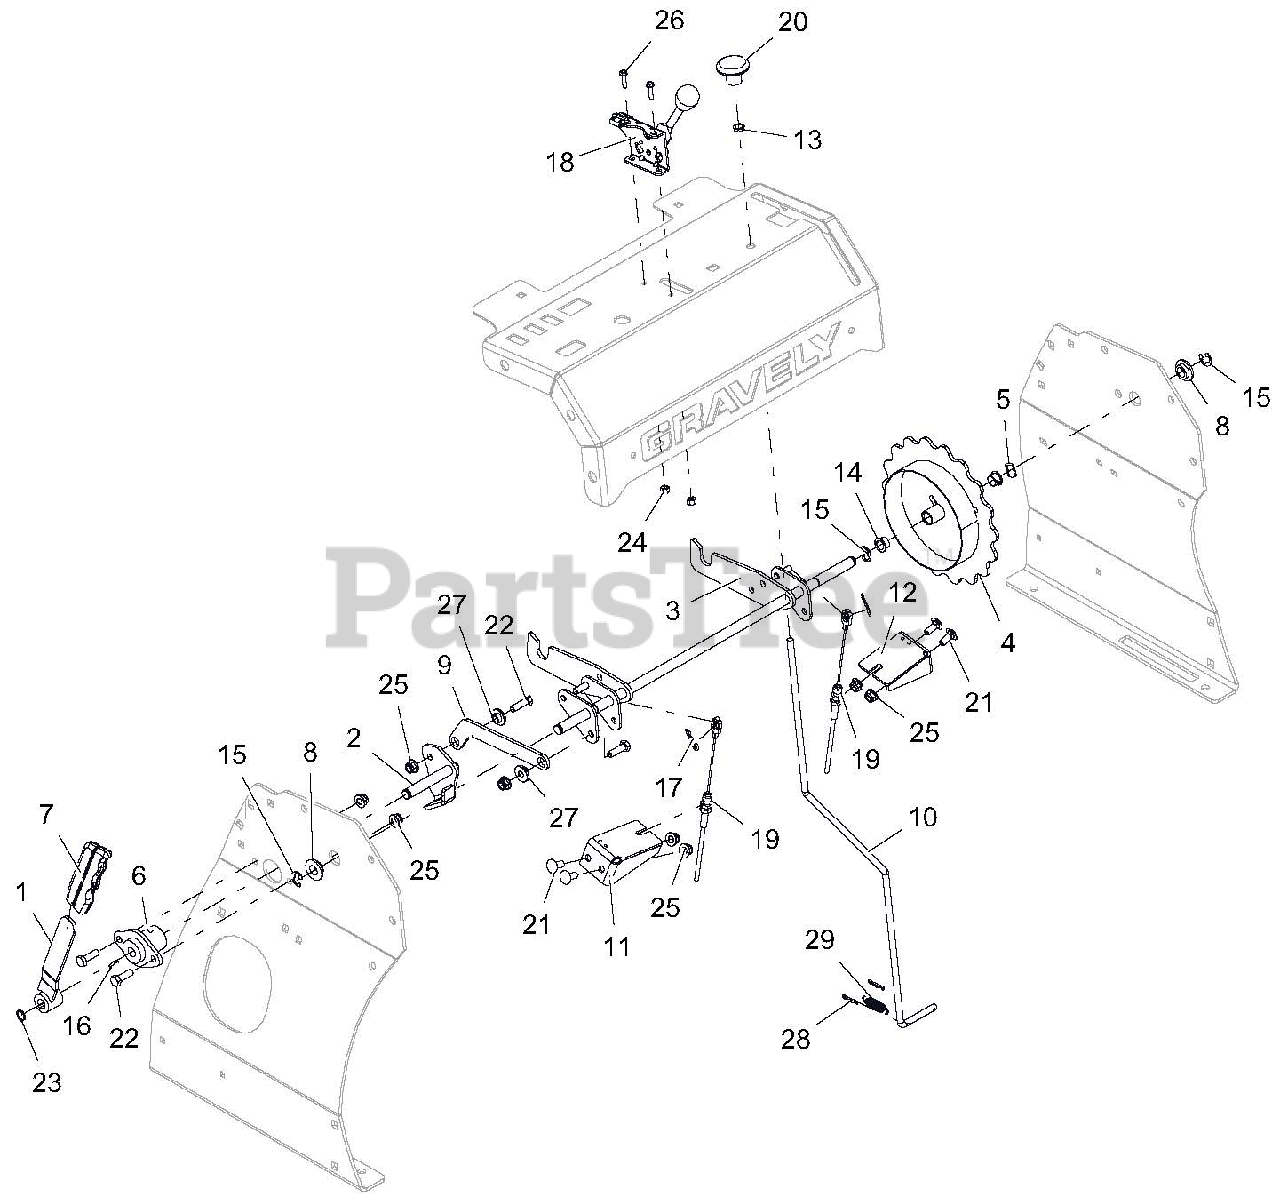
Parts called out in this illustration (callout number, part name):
1	WLDMT, PARKING BRAKE LEVER
2	WLDMT, PARKING BRAKE ACTUATING
3	WLDMT, BRAKE INTERLOCK
4	WLDMT, HEIGHT OF CUT
5	WAVE WASHER .531X.781X.125 FH
6	BSHG, FLANGE .500 ID
7	GRIP, PARKING BRAKE
8	BSHG, FLANGE .515X.750X.31X1.12
9	LINK, INTERLOCK
10	WIREFORM, TRAILER LOCK
11	BRKT, CABLE MTG.
12	BRKT, LH CABLE MTG
13	BSHG, POLYLINER-.38 SNAPIN
14	BUSHING, POLYLINER - .50 SPLIT
15	RG-RTNG-EXT .500X.042 (E)
16	KEY, WDRF .13x.63 HRD#5 GM124545 P
17	PIN, HAIR INT .08X.18X1.18 YWZC
18	CABLE, PRO-CONTROL THROTTLE
19	CABLE, PROSTANCE P. BRAKE
20	KNOB, PUSH -PULL .312-18
21	BLT-RDHDSQNK .31-18X.75 G5 YWZC
22	BLT-HEX .31-18X1.00 GR5 YWZC
23	RG-RTNG-EXT .500x.050
24	NUT-LK-NYL #10-24 YWZC
25	NUT-LK-NYL-FLG .31-18 YWZC
26	@SCR-MCH 10-24X.75 HWH YWZC
27	BSHG, FLG .32X.500.344X.880
28	PIN-HAIR, ENDRIES #25 YWZC
29	SPRG, EXTENSION
